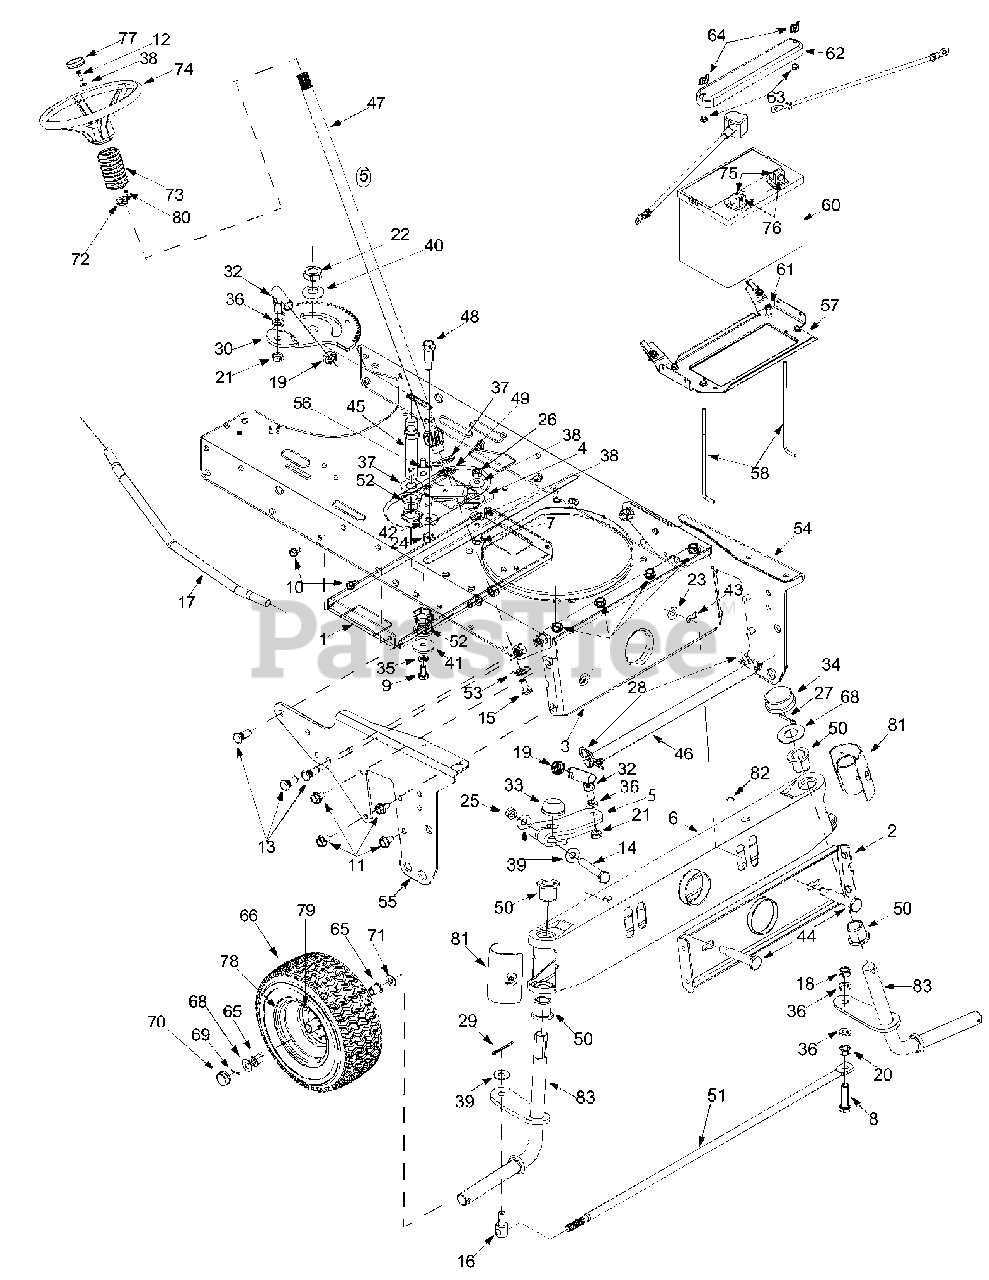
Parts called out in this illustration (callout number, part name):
7	Hex Bolt 5/16-24 x 1.0"
8	Hex Bolt 3/8-24 x 1.50"
9	Hex Bolt 5/16-18 x 0.625"
10	TT Screw 1/4-20 x 0.5"
11	TT Screw 5/16-18 x 0.625"
12	Hex Bolt 5/16-18 x 1.0"
13	Rib Neck Rd. Bolt
14	Hex Bolt 3/8-24 x 2.5"
15	Pan Hd. Machine Screw
16	Ferrule
17	Steering Drag Link
18	Hex Lock Nut 3/8-24
19	Jam Nut
20	Hex Nut 3/8-24
21	Lock Nut
22	Jam Nut
23	Flange Lock Nut
24	Hex Nut 3/8-16
25	Lock Nut
26	Hex Nut
27	Cotter Pin
28	Hairpin Clip
29	Cotter Pin
30	Steering Gear Segment: 25T
31	Loctite (TM) 242
32	Ball Joint
33	Push Cap
34	Hub Cap
35	Lock Washer
36	Lock Washer
37	Flat Washer
38	Beleville Washer
39	Flat Washer
40	Bell Washer
41	Flat Washer
42	Bell Washer
43	Grease: Alvania (TM) EP2
44	Shoulder Screw
45	Steering Gear Shift Segment
46	Deck Rod
47	Steering Shaft
48	Shoulder Screw
49	Hex Flange Bearing
50	Flange Bearing
51	Tie Rod
52	Hex Flange Bearing
53	Cap
60	Battery
61	Hex Washer B-Tap Scr.
62	Battery Cover
63	Hex Nut
64	Wing Nut
65	Flange Bearing
66	Wheel, See "Wheels, Front"
68	Flat Washer
69	Cotter Pin
70	Hub Cap
70	Hub Cap (Gray)
70	Hub Cap (Beige)
70	Hub Cap (Yellow)
71	Flat Washer
72	Flange Bearing (Style A only)
73	Steering Bellow (Style 0, 3,5,9)
73	Steering Bellow (Style A)
74	Steering Wheel
75	Hex Lock Nut
76	Hex Bolt 1/4-20 x .75"
77	Steering Cap (Round)
77	Steering Wheel Cap (Square)
78	Rim, See "Wheels, Front"
79	Air Valve
80	Oval Hd. C-Sunk Screw
81	Pivot Bar Cap End
82	Grease
83	Axle Assembly LH: Front
83	Axle Assembly RH: Front
